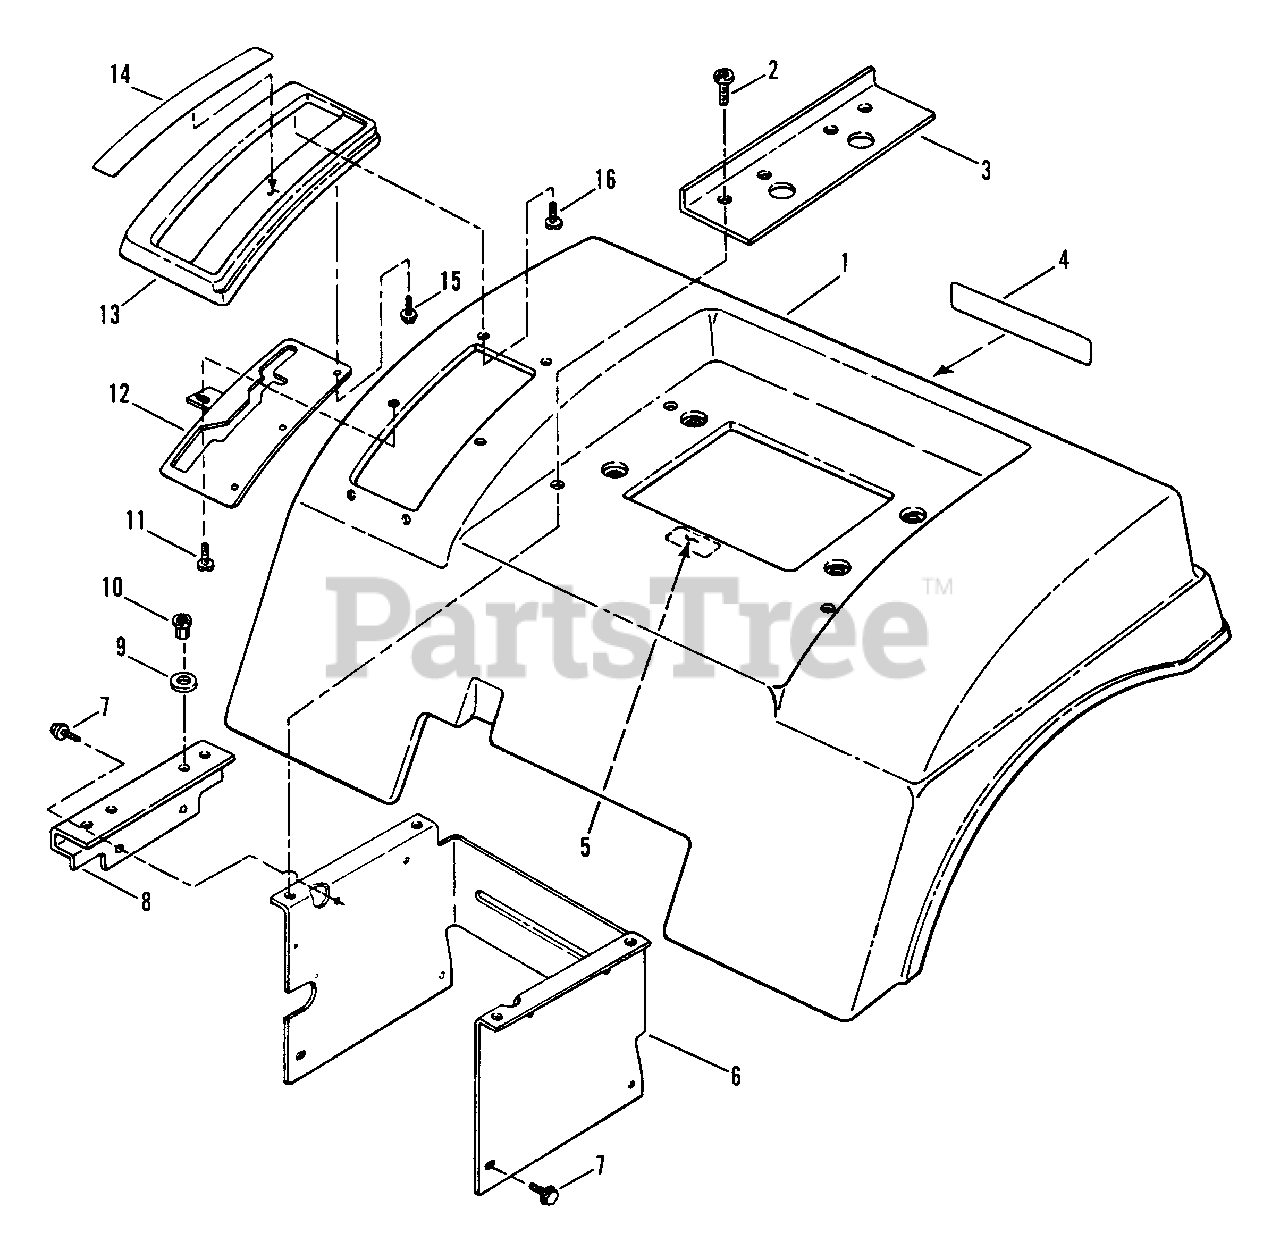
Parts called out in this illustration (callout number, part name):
1	PAN, Seat (Fender)
2	SCREW, 5/16-18 x 5/8" Truss Head (Torx)
3	BRACE, Fender
4	DECAL - SNAPPER, Molded Logo (Chrome)
5	DECAL - CAUTION, Battery Installation
6	SUPPORT, Fender
7	SCREW, 5/16-18 x 5/8" Hex Washer Head, Self-Tapping
8	BRACKET, Fender Support
9	WASHER, Flat
10	RIV-NUT, 5/16-18
11	SCREW, #10-16 x 3/4" Pan Head, Self-Tapping
12	DETENT, Gear Shift
13	COVER, Shift
14	DECAL, Shift Cover, 6-Speed
15	SCREW, #10-16 x 1/2" Hex Washer Head, Self-Tapping
16	SCREW, #10-16 x 5/8" Pan Head, Self-Tapping
